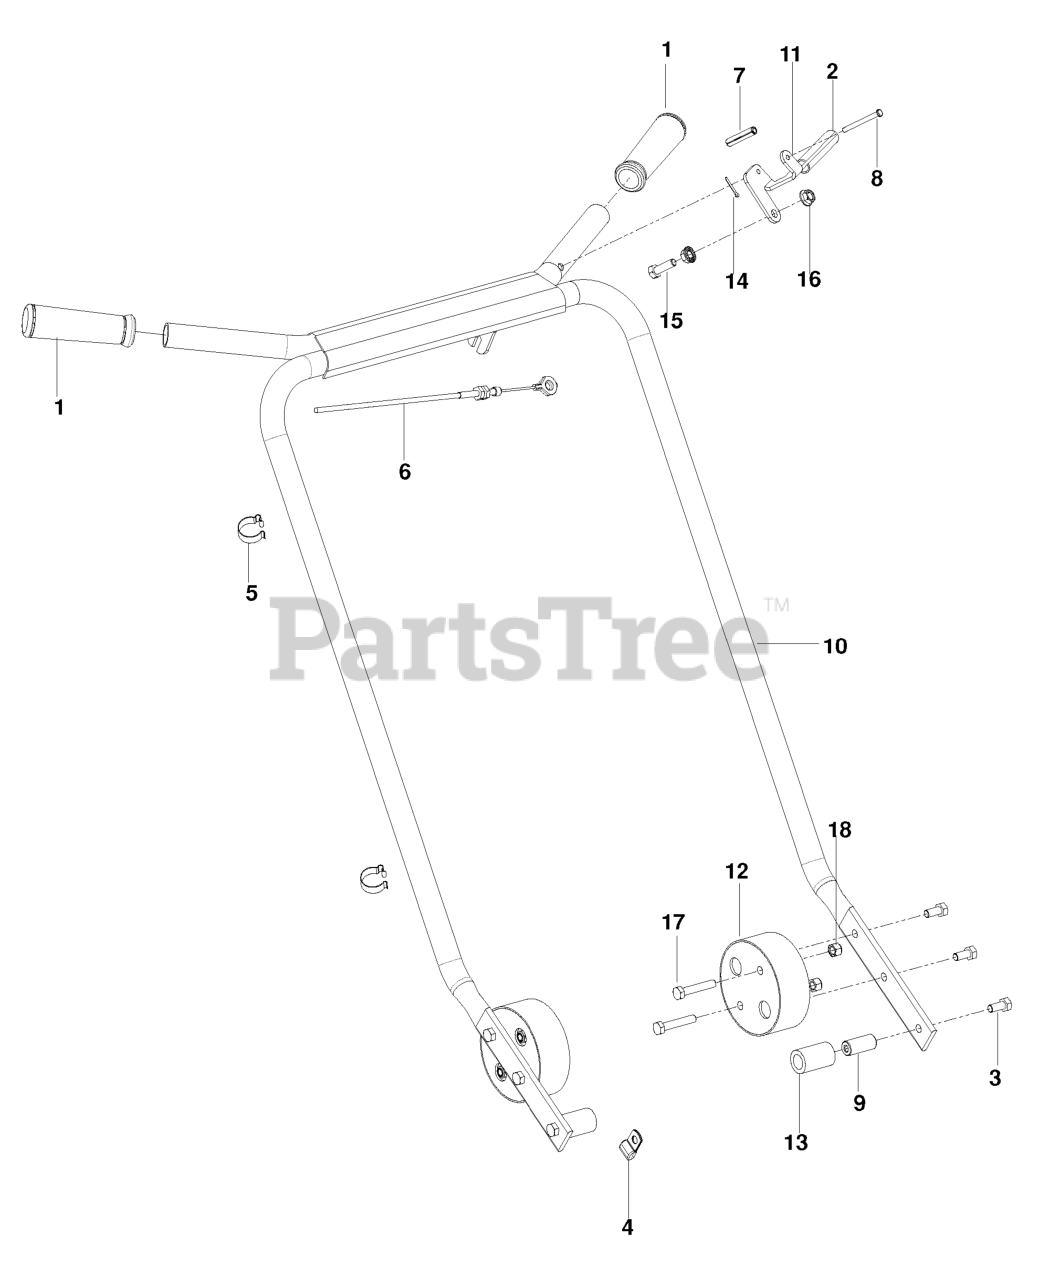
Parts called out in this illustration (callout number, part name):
1	IMPELLER KIT, 3.5/5HP
3	HCS M8-1.25 X 22MM GR 8.8 ZD
4	DOUBLE TUBE CLAMP
5	CLIP - CABLE
6	CABLE - PULL
7	5/16" DIA ROLL PIN X 1.5
8	PIN, CLEVIS
10	HANDLE - GREY
11	LEVER - THROTTLE, ORANGE
12	MOUNT, VIBRATION
13	BUSHING, POLYURETHANE
14	COTTER PIN 3/32 X 3/4
15	HCS 5/16C X 1
16	NUT 5/16C WHIZ
17	HCS 5/16C X 1 3/4
18	NUT 5/16 NYLOC
